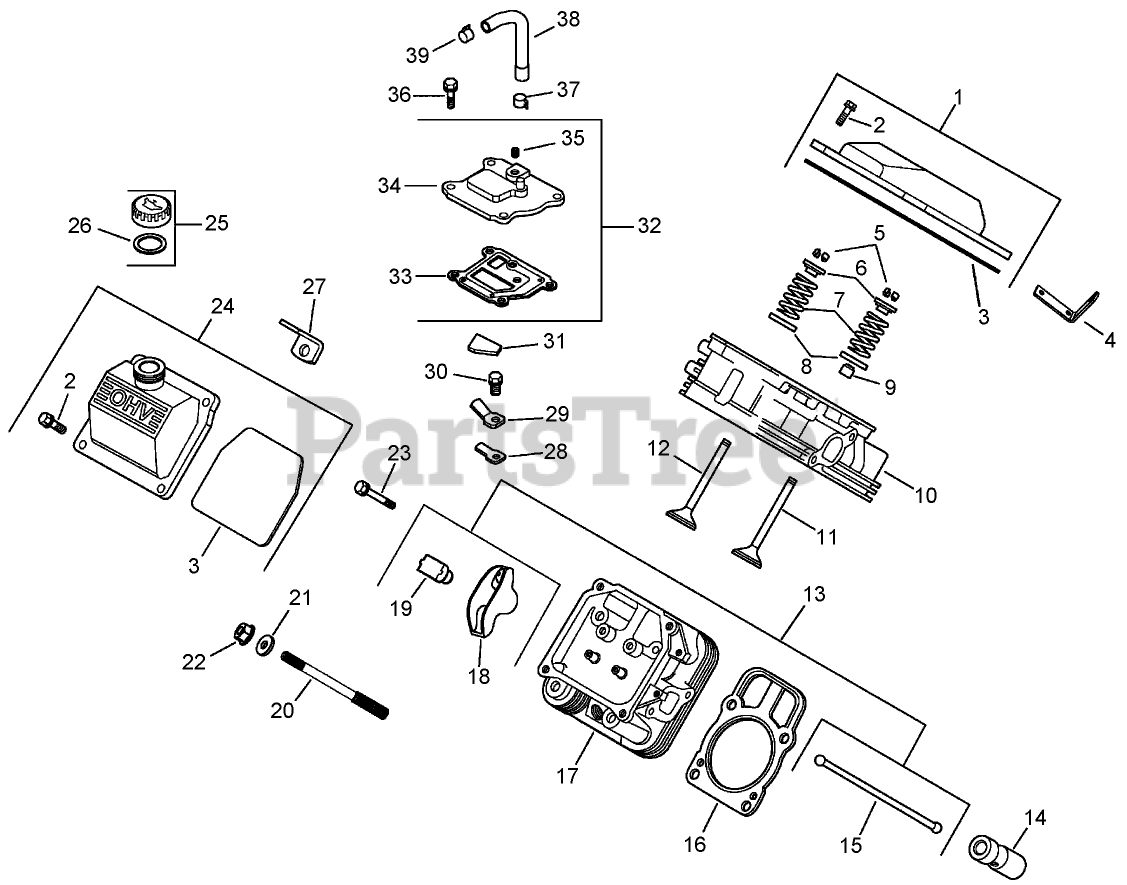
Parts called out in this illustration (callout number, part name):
1	Plain Valve Cover Kit (Includes 2, 3)
2	SCREW-FLANGE (M6X1.0X30)
3	O-Ring
4	STRAP-LIFTING
5	RETAINER KIT
6	CAP-SPRING, VALVE
7	SPRING-VALVE
8	RETAINER-SPRING
9	SEAL-STEM, VALVE
10	Head ASM (No. 1 Cylinder)
11	VALVE-INTAKE (STD)
11	VALVE-INTAKE (.25)
12	VALVE-EXHAUST (STD)
12	VALVE-EXHAUST (.25)
13	Valve Train Kit (Includes 15, 18, 19)
14	HYDRAULIC VALVE LIFTER KIT
15	ROD-PUSH
16	Cylinder Head Gasket Kit (Includes 21, 22)
17	Head ASM (No. 2 Cylinder)
18	ARM-ROCKER
19	Pivot-Arm, Rocker
20	STUD (M8X1.25xM10X1.5x105MM)
21	WASHER-FLAT (8.6 MM)
22	NUT-FLANGE (M8X1.25)
23	SCREW-FLANGE (M6X1.0X34)
24	Oil Fill Valve Cover Kit (Includes 2, 3)
25	Oil Fill Cap ASM (Includes 26)
26	O-Ring
27	Strap-Lifting
28	REED-BREATHER
29	RETAINER-REED
30	SCREW-HHFTF (M5X.80X10)
31	Filter-Breather
32	Breather Kit (Includes 33-35)
33	GASKET-BREATHER
34	COVER-BREATHER
35	PLUG-PIPE, COUNTERSUNK (1/8)
36	SCREW-HHFTF (M6X1.0X20)
37	CLAMP-HOSE, SPRING (1/2)
38	Hose-Breather
39	Clamp-Hose
